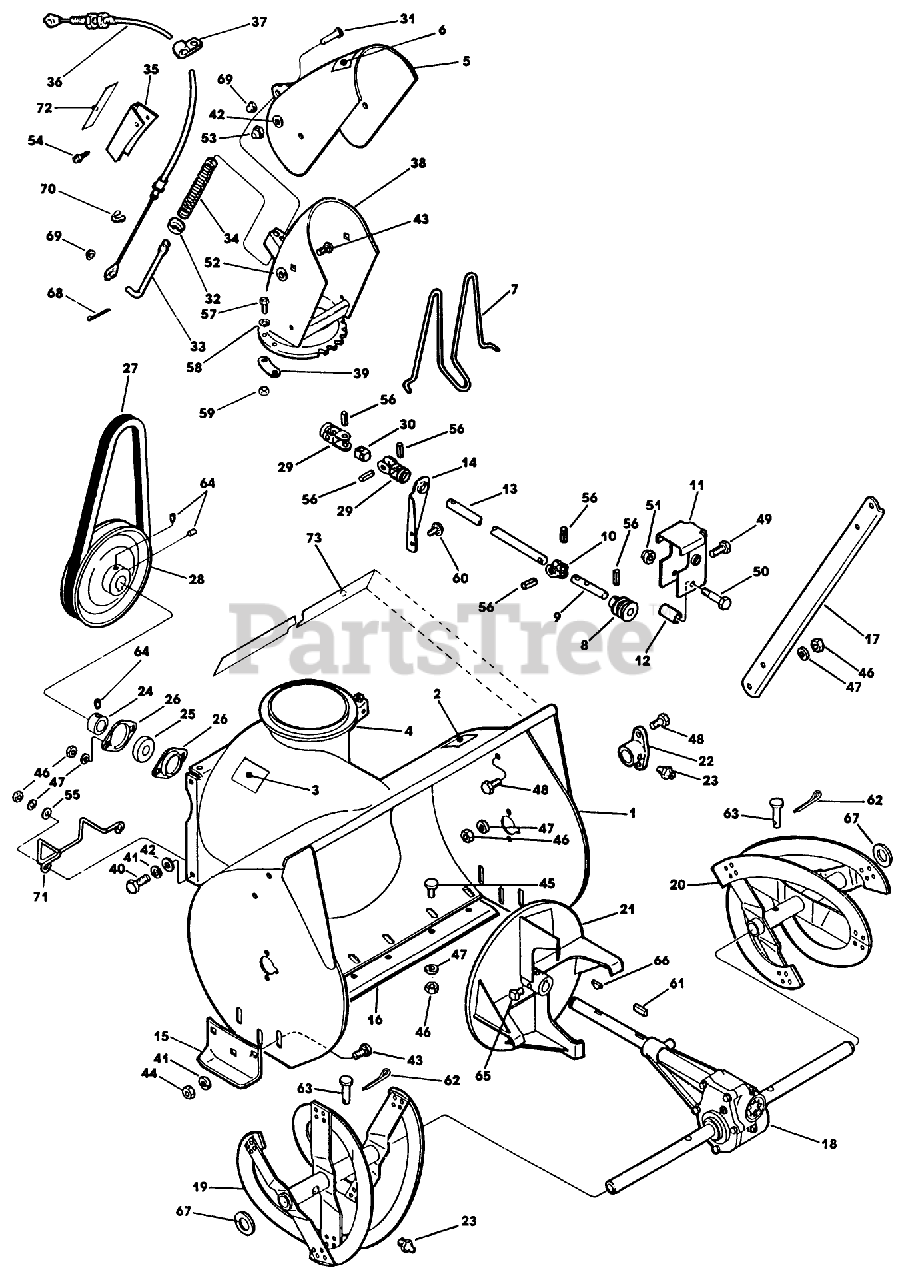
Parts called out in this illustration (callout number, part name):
16	SCRAPER
21	IMPELLER ASSEMBLY (12)
24	COLLAR-BEARING
25	DISCONTINIUED
26	FLANGETTE-BEARING
27	V-BELT
28	PULLEY ASM
30	PIVOT PIN
39	HOLD DOWN CHUTE
41	WASHER
42	WASHER
44	NUT
46	NUT SS
48	SCREW - HEX
51	NUT-LOCK, CONE
53	NUT-LOCKING
54	SCREW S
57	SCREW
58	WASHER - LOCKING
60	SCREW-HWH
63	PIN-CLEVIS
64	SET SCREW
66	KEY
70	RET. RING
71	LWR AUGER BELT GUIDE
